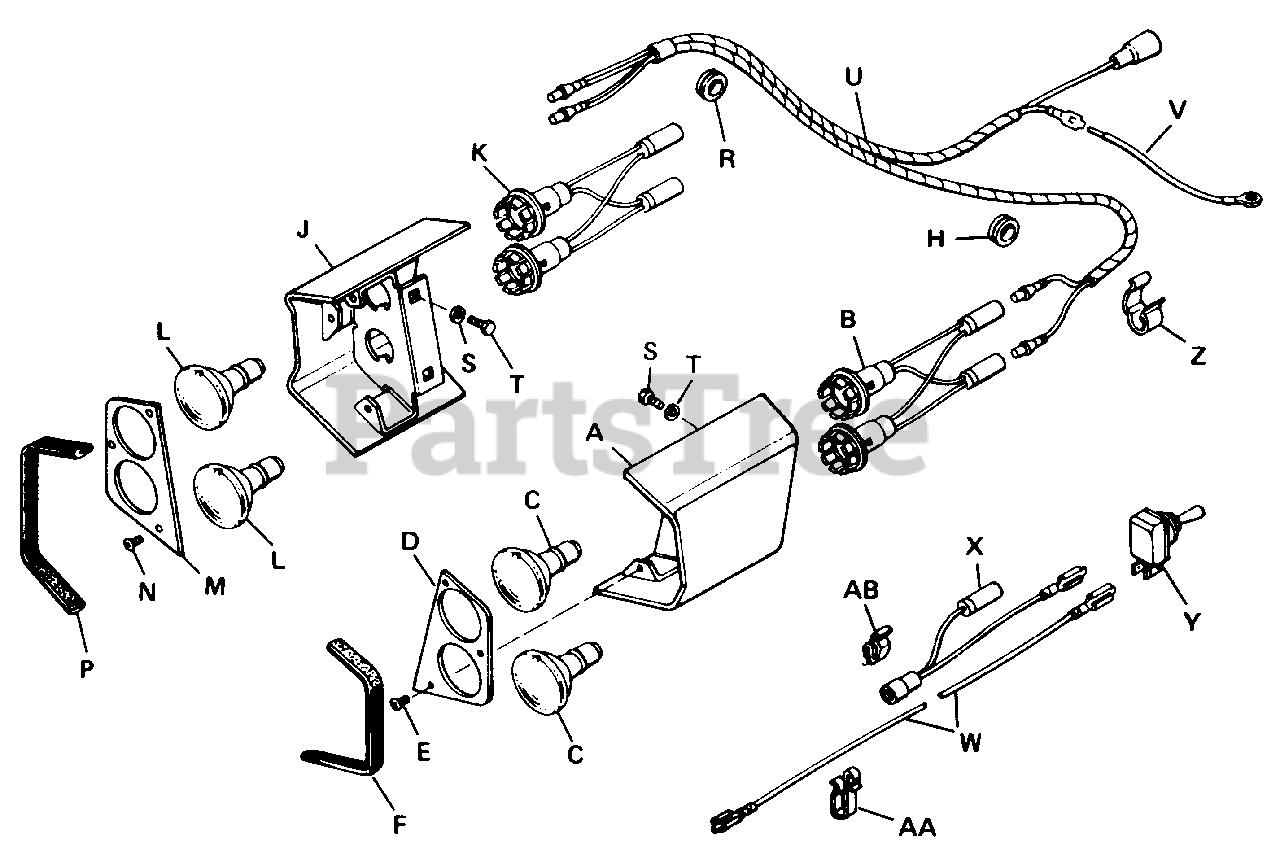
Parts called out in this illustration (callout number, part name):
A	Shroud & Plate Assy. L.H.
B	Lamp Socket & Wire Assy.
C	Headlight
D	Plate, Front
E	Screw, Round Head Phillips Swageform No. 12-24 x 1/2"
J	Shroud & Plate Assy. R.H.
K	Lamp Socket & Wire Assy.
L	Headlight
M	Plate, Front
N	Screw, Round Head, Phillips Swageform No. 12-24 x 1/2"
S	Hex Cap Screw, 1/4"-20 N.C. x 1/2"
T	Lock Washer, 1/4" Std.
U	Harness Assy.
V	Wire Assy., Ground
W	Wire Assy., Light Switch
X	Wire Assy., Indicator Lamp
Y	Switch, Toggle
Z	Cable Clip Tinnerman, Front Frame
AA	Cable Clip Tinnerman, Rear Frame
AB	Cable Clip Tinnerman, Top of Grille
